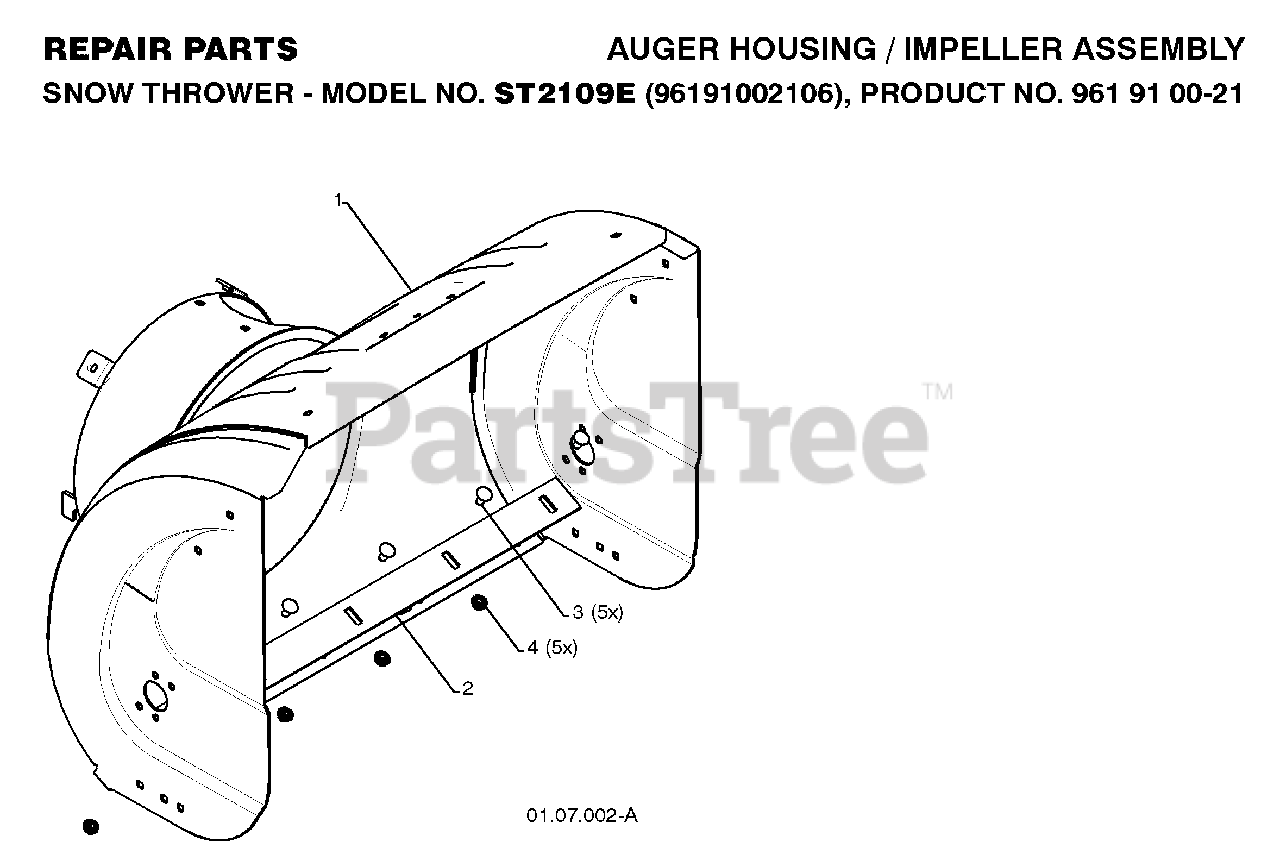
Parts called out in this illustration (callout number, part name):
2	BAR, SCRAPER
3	BOLT
4	NUT.FLANGE.5/16
